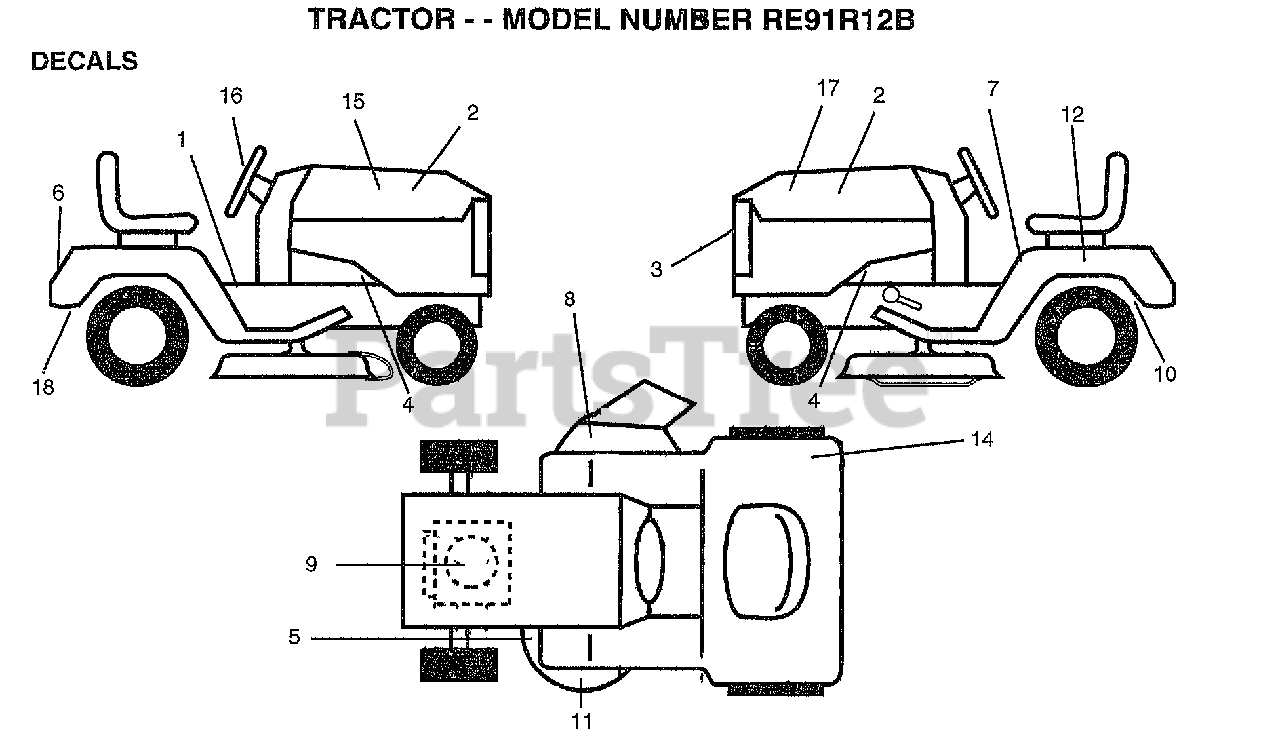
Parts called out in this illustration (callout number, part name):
1	DECAL CLUTCH/BRAK
2	"DECAL INSERT,HOOD"
3	GRILL DECAL
4	"DECAL CHASSIS,HOT"
5	DECAL.V.BELT
6	FENDER DECAL
7	DECAL.READ.O.MANU
8	DECAL.DANGER.CUTF
9	DECAL, ENGINE
10	DECAL.DRAWBAR.LDL
12	DECAL.BATRY.3-3908
15	DECAL HD RLY RH
16	"DECAL,STR WHL"
17	DECAL HD RLY LH
18	DECAL.EURO.ST.CE.
